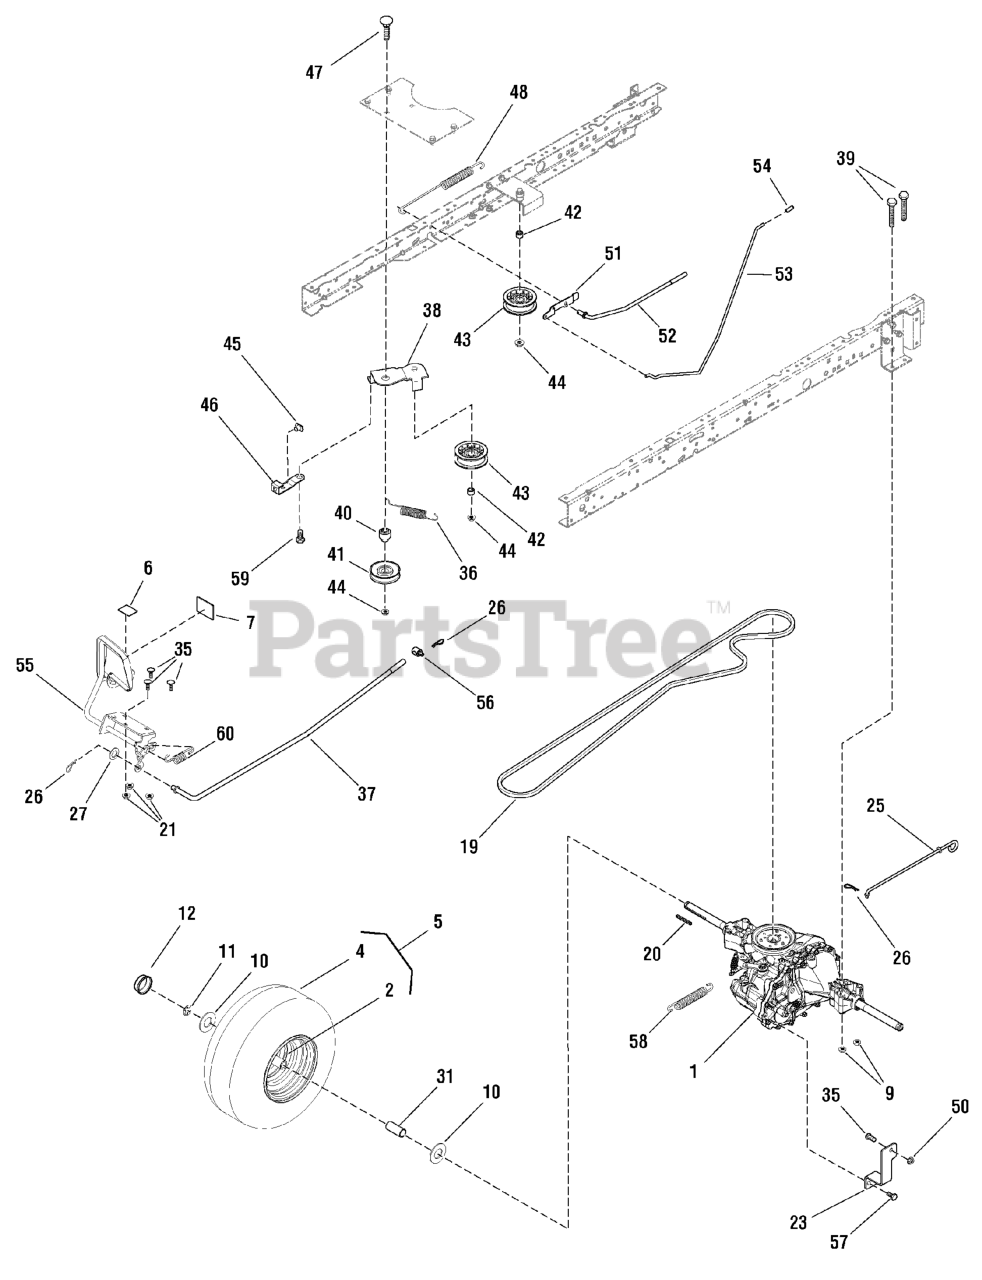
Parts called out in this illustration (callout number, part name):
1	TRANSAXLE, Hydro T2
2	VALVE STEM & CAP
4	TIRE, 18 x 8.5-8 2 Ply K358
5	WHEEL & TIRE ASSEMBLY, 18 x 8.5-8
6	MAT, Toe
7	PAD, Hydro Pedal
9	NUT, Hex Flange Centerlock, 5/16-18
10	WASHER, Flat
12	HUB CAP
19	V-BELT, Drive, 4L, 88.96"
20	KEY, Square, 3/16
21	NUT, Hex Flange, 5/16-18
23	BRACKET, Torque T2
25	ROD, Roll Release
26	HAIR PIN, .56D-.092T
27	WASHER, Flat, 3/4
31	SPACER, Axle
35	BOLT, Carriage, 5/16-18 x 5/8
36	SPRING, Extension
37	ROD, Drive
38	ARM ASSEMBLY, Idler
39	BOLT, Hex, 5/16-18 x 2-1/2
40	BUSHING, Pivot
41	PULLEY, Idler, 3"
42	SPACER, 1/2" to 17mm
43	PULLEY, Idler, 2-3/4"
44	NUT, Flange Lock, 3/8-16
45	NUT, Tee
46	LINK, Clutch, Yellow
47	BOLT, Carriage, 3/8-16 x 2
48	SPRING, Hydro Brake T2
50	NUT, Hex Flange, 5/16-18
51	LATCH, Parking Brake, Yellow
52	ROD, Clutch Drive
53	ROD, Parking Brake
55	PEDAL, Hydro
56	NUT, Adjusting
57	BOLT, Hex Head, 5/16-18 x 2
58	SPRING, Extension
59	BOLT, Shoulder, 3/8-16 x 1
60	SPRING, Extension
